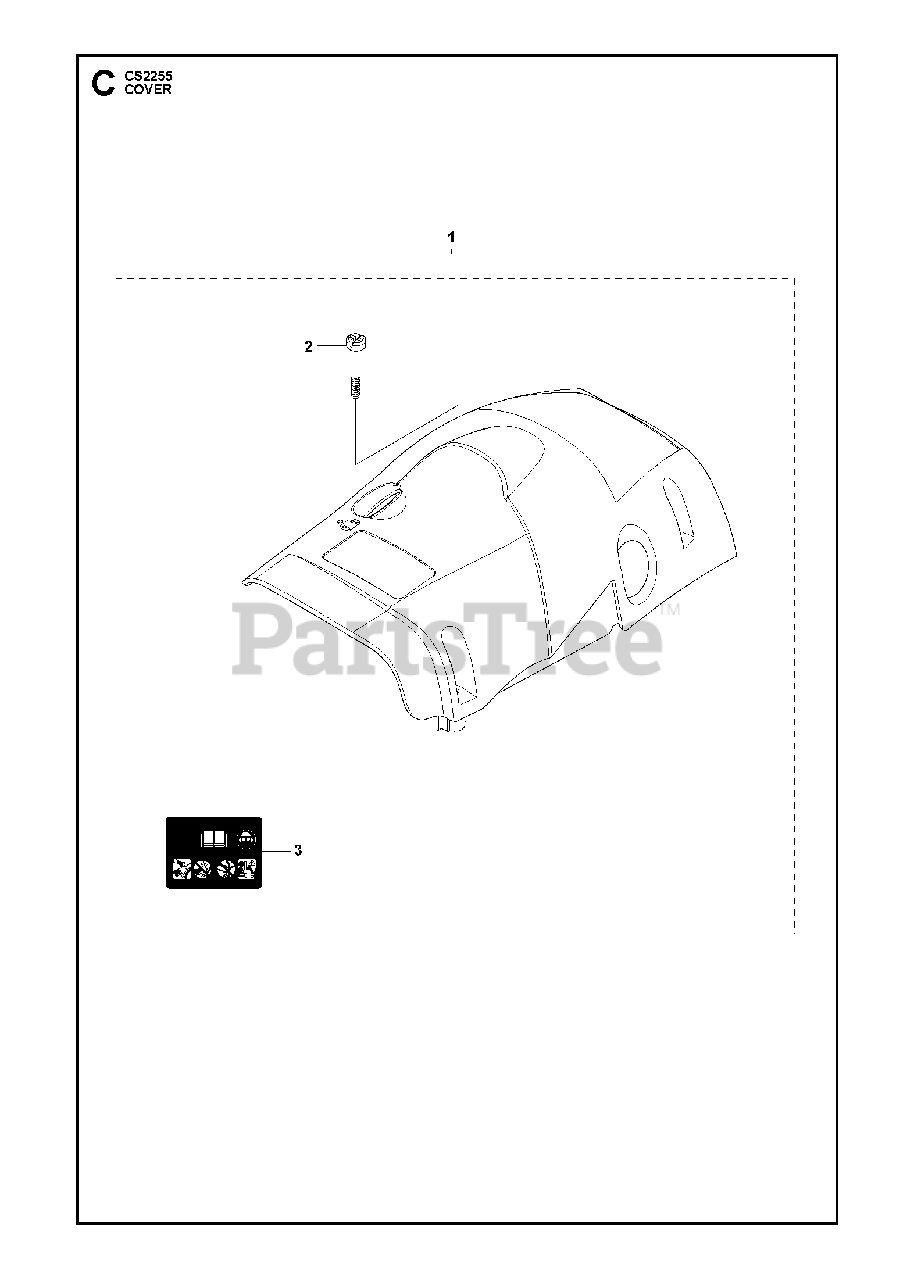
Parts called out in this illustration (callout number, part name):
1	CYLINDER COVER
2	SCREW
3	DECAL
